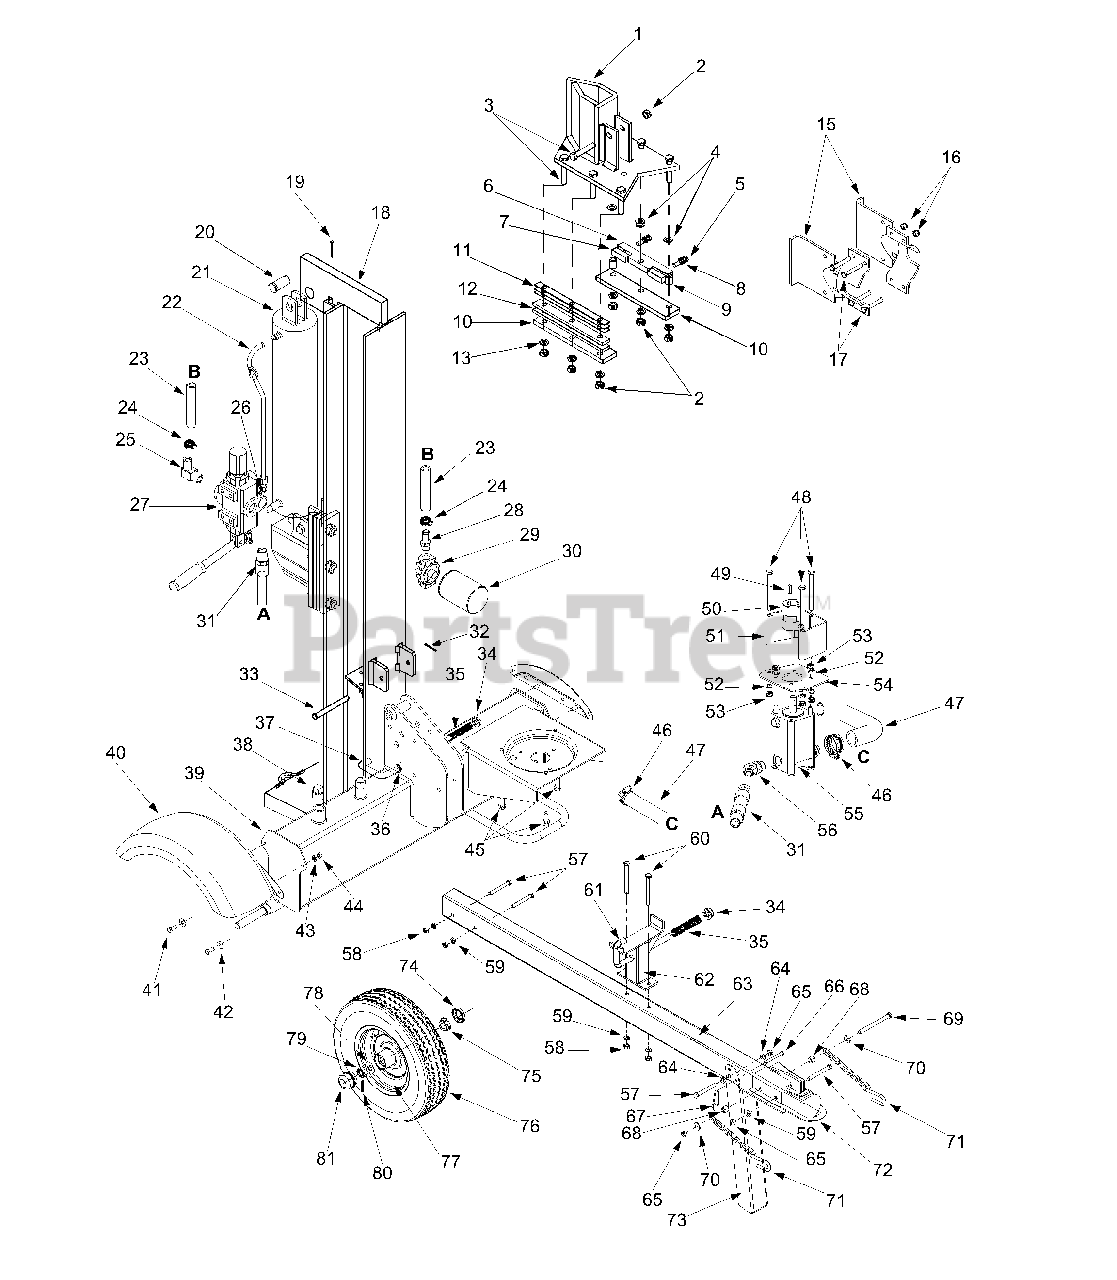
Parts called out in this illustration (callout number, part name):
2	Lock Nut 1/2-20
3	Hex Cap Screw 1/2-20 x 2.75
4	Flat Washer .531 x .93 x .090
5	Hex Cap Screw 3/8-24 x 1.5
8	Hex Jam Nut 3/8-24
9	Spacer
13	Lock Washer 1/2
17	Hex Cap Screw 3/8-16 x 2.5
20	Clevis Pin
22	Hydraulic Tube
23	Return Hose 3/4" ID x 44" Lg
24	Hose Clamp 5/8"
25	Return Elbow
26	90 Degree Solid Male Adapter
28	3/4" Hose Adapter
29	Filter Housing
30	Oil Filter
31	High Pressure Hydraulic Hose
32	Cotter Pin 1/8" Dia
33	Hinge Pin 1/2 x 4.8" Lg.
34	Push Cap
35	Comp. Spring 4" Lg.
36	Flat Washer .635 ID x .93 OD
37	Locking Rod
38	Pipe Plug
42	5/16 Washer
43	Lock Washer 5/16
44	Hex Nut 5/16-24
45	Hex Washer Screw 3/8-16 x 1.
46	Hose Clamp
47	Suction Hose
48	Hex Screw 5/16-24 x 3.25
49	Sq. Key 3/16" x .75
50	Flexible Coupling .750 x .500
50	Flexible Coupling .875 x .500
50	Flexible Coupling .875 x .437
51	Coupling Shield
52	L-Washer 5/16" ID
53	Hex Nut 5/16-24
55	Gear Pump (11 gpm)
55	Pump Kit
55	Gear Pump (9.5 gpm)
56	45 Degree Elbow
57	Hex Bolt 3/8-16 x 3" Lg.
58	Hex Nut 3/8-16
59	L-Washer 3/8" ID
60	Hex Bolt 3/8-16 x 4" Lg.
61	Locking Rod
64	Flat Washer 3/8
65	Hex Lock Nut 3/8-16
66	Clevis Pin 5/16 x 2.5"
67	Spring Pin
68	Spacer 3/8" ID x .625' OD
69	Hex Bolt 3/8-16 x 4" Lg.
70	Flat Washer 3/8" ID x .87" OD
71	Chain - Tow Hitch
72	Hitch Coupler
75	Bearing Cone
76	Wheel Assembly
77	Rim Assembly - Gray
78	Flat Washer .76" ID x 1.5" OD
79	Slotted Nut 3/4-16
80	Cotter Pin 5/32" x 1-1/4" Lg.
81	Hub Cap
